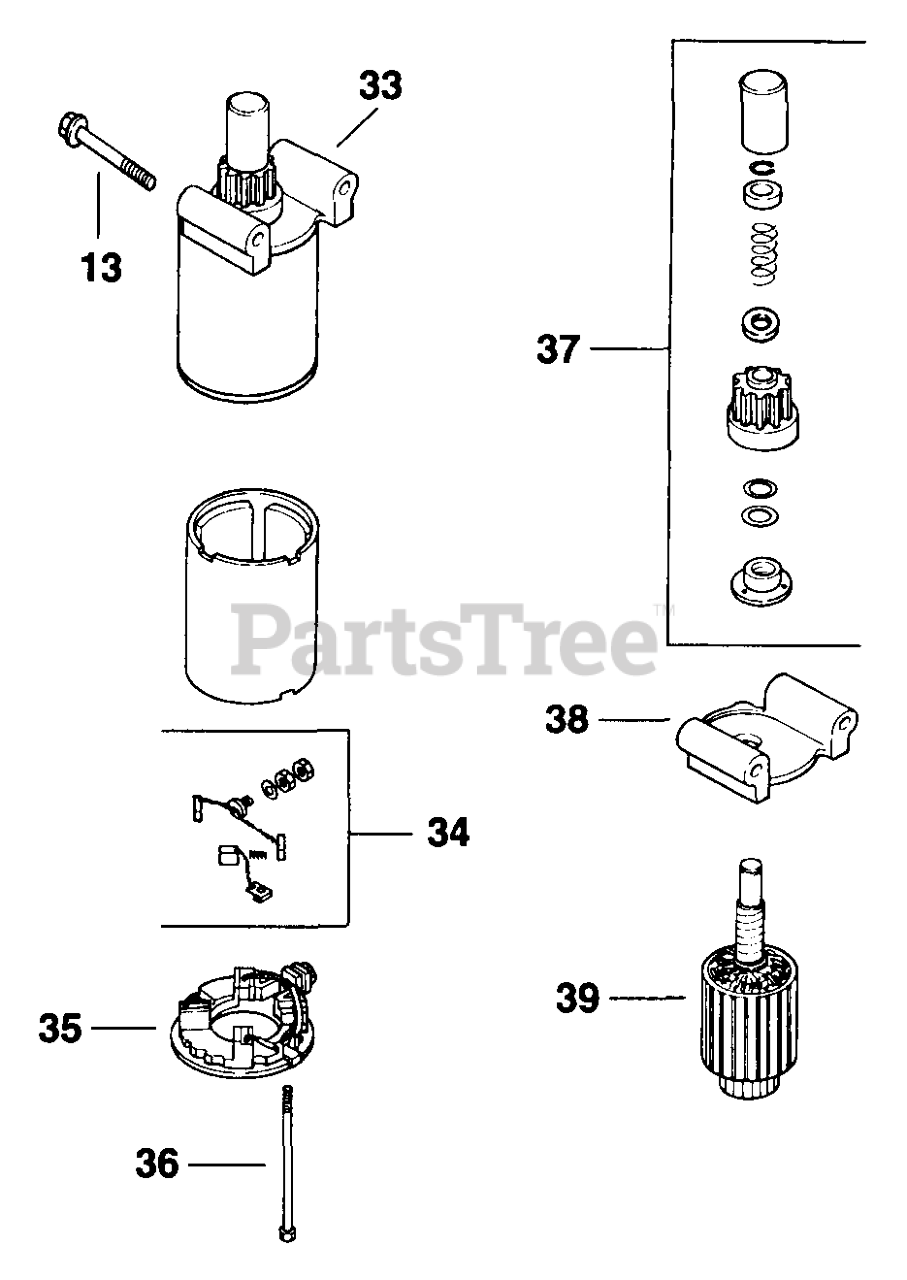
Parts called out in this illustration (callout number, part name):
34	Kit, Brush & Spring
35	Cap, Commutator End
36	Screw, Hex. Flange 1/4-20x4-5/8"
37	Kit, Drive
38	Cap, Drive End
39	Armature
